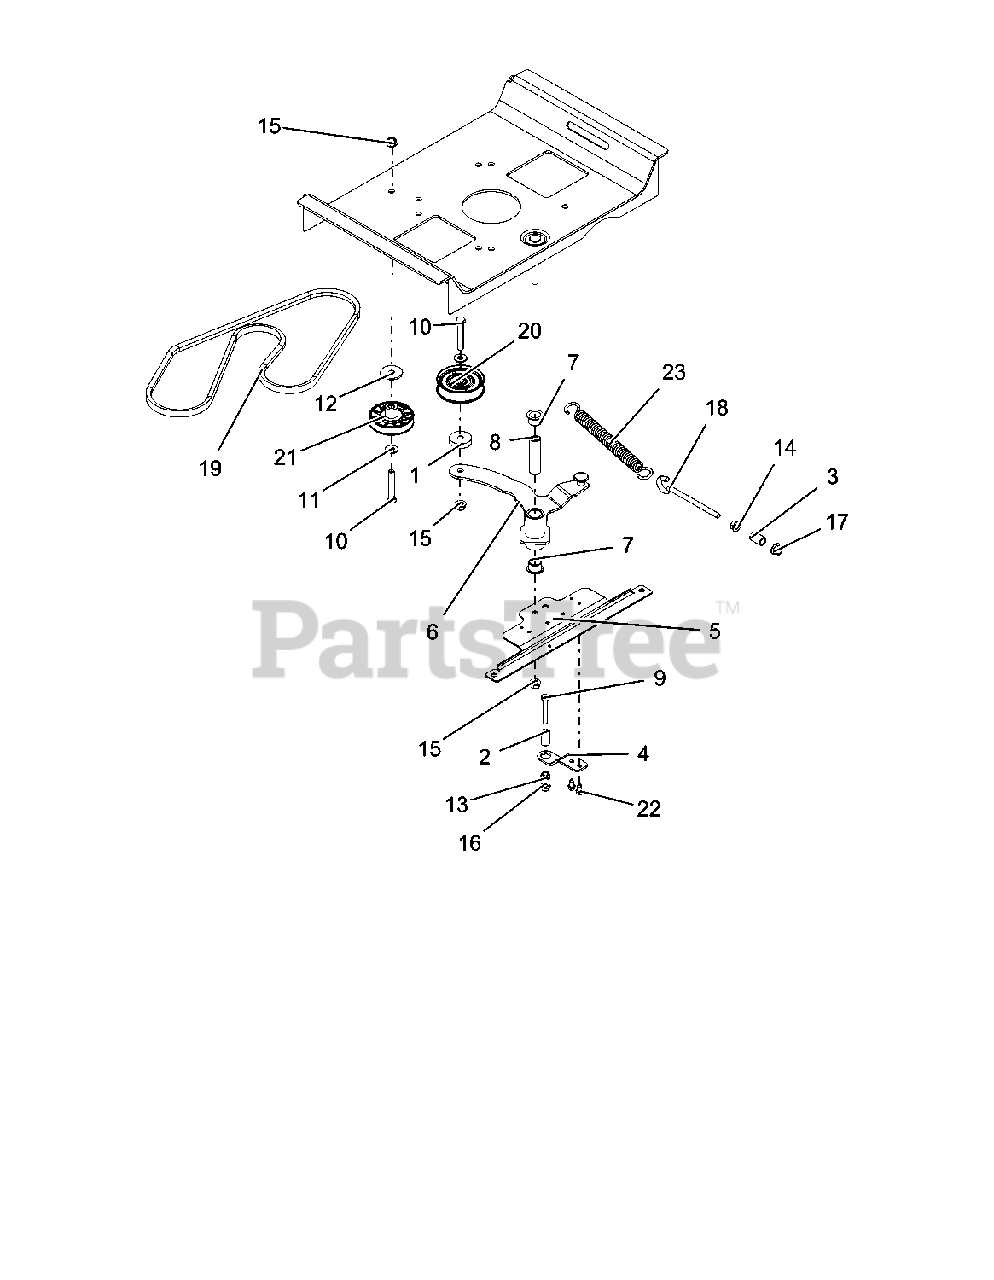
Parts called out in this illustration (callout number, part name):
1	SPACER, .39 X 1.50 X .380
2	SPACER, RUBBER 5/16 IDX1.0 LG
3	SPACER, .375X.625X.970 (PM)
4	BRKT, CLUTCH STOP
5	BRKT, DRIVE IDLER MOUNTING
6	WLDMT,GRD DRIVE IDLER ARM-LGR
7	BSHG-FLG 0.75X0.875X.625X1.125
8	BUSHING, SLEEVE .38X.750X2.78
9	@BLT-HEX .31-18X2.00 GR5 YWZC
10	@BLT-HEX .38-16X2.25 GR5 YWZC
11	@WSHR-FL-STL.38X.875X.083 YWZC
12	WSHR-FL-STL .380X1.50X.125YWZC
13	@NUT-SPNLK-FLG .312-18 YWZC
14	@NUT-SPNLK-FLG .375-16 YWZC
15	@NUT-LK-TOP-FLG .38-16 YWZC
16	@NUT-LK-TOP-FLG .31-18 YWZC
17	@NUT-LK-NYL-FLG .38-16 YWZC
18	BOLT,.38-16 X 4.25-.62 DIA EYE
19	V-BELT, A-RAW EDGE
20	IDLER, FLAT - 3.05" X .75"
21	IDLER-V 3.00" COMPOSITE
22	SCR-TAP .25-20X.50 HWH TR YWZ
23	SPRING, EXTENSION
